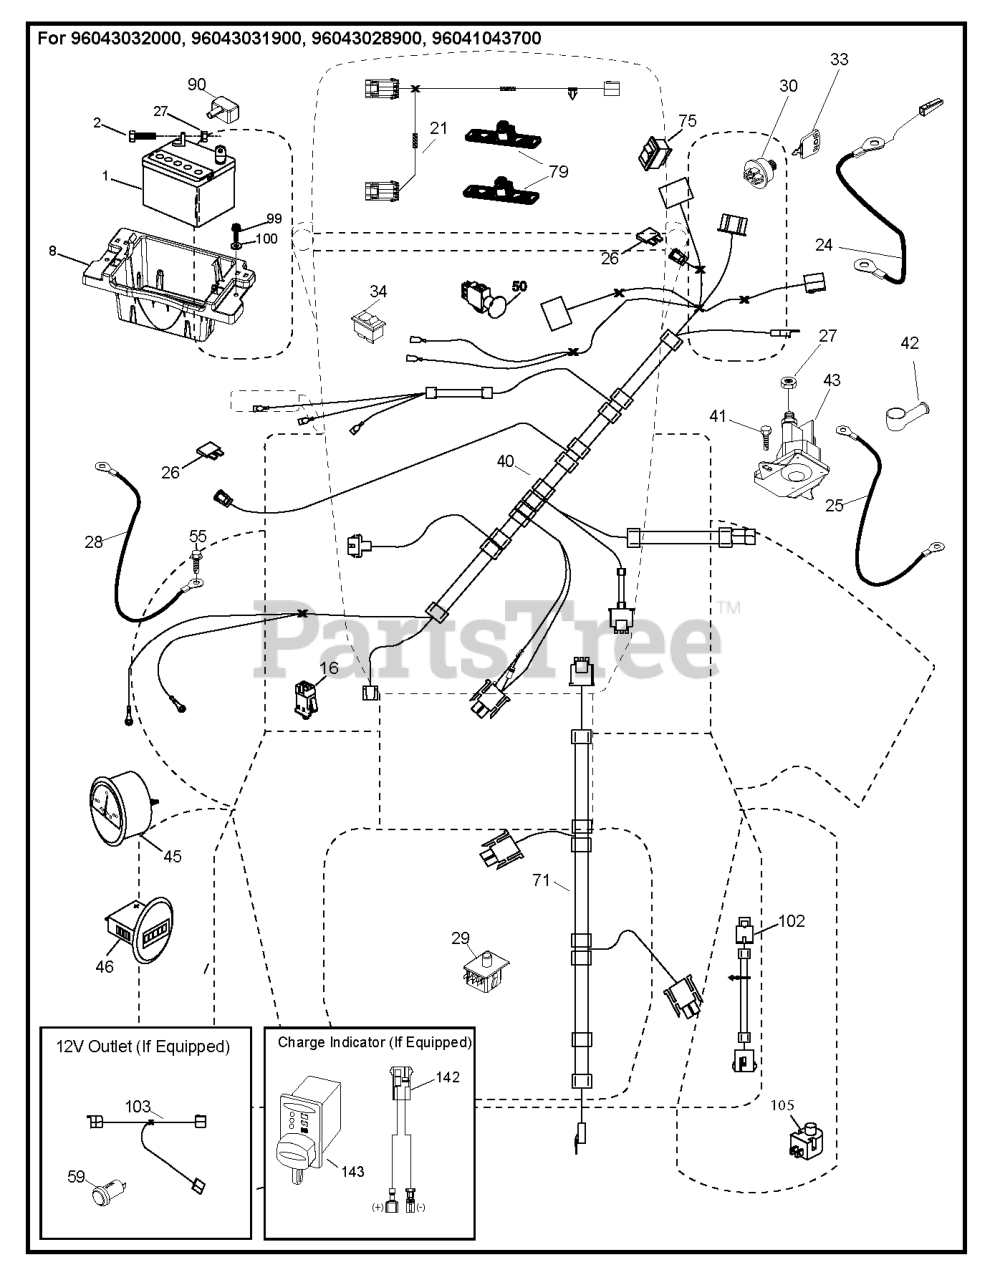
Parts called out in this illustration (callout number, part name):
1	Battery 12 Volt 25 Amp
2	BOLT.HEX.1/4.X.3/4.DICHROMATE
8	TRAY.ASM.BATTERY.FRT.TEX.CARB
16	SWITCH INTERLOOK PUSH-IN
21	HARNESS LIGHT ASSY TRACTOR,
21	Harnesses
24	CABLE.FRBATT.W/WIRE.8GA.8
25	CABLE.STARTER.8GA.17.5
26	FUSE 20AMP
28	CABLE.GROUND.21"BLK.8GA.90T
29	SWITCH.SEAT.DP W/RAMPS
30	SWITCH.IGN.DELTA.W.LGH.ROS
33	KEY.CHAIN.BLISTER.PACK.GEN.INT
33	KEY.CHAIN.BLISTER.PACK.GEN.USA
40	Harnesses
40	HARNESS.DASH.EDIFF.RND.CHG
41	SCREW
42	TERMINAL COVER
50	RP SWITCH.PTO.TERMINAL.STD.RED
50	SWITCH.PTO.8TERMINAL.STD.BLK
55	SCREW 5/16"
71	HARNESS.IGN.CHASSIS.TEX.DCKLOC
75	SWITCH.ON/OFF.(DIFF.LOCK)
79	Light
79	LED LIGHT.LH
79	LED LIGHT.RH
90	COVER.TERMINAL.BATTERY
99	SCREW HEXWSHR 1/4-20X3/4
102	HARNESS PIGTAIL PCH TEX ROS
103	HARNESS.PIGTAIL.12V.OUTLET.
105	REVERSE SWITCH
143	CHARGE.PORT
